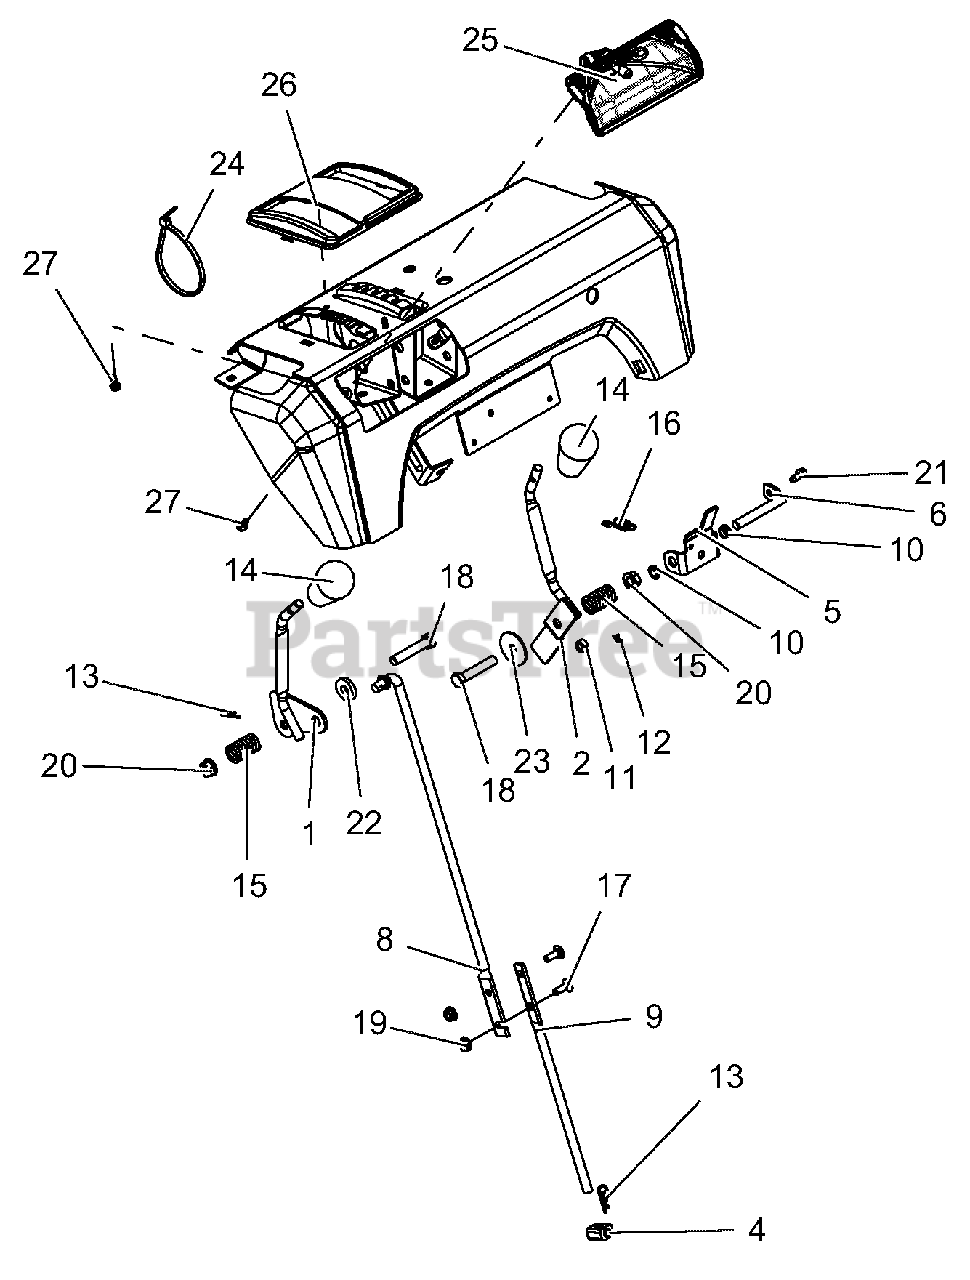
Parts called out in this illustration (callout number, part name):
1	WELDMENT, CONTROL LEVER(SHIFT)
2	WELDMENT, CONTROL LEVER (DEFL)
4	PIVOT,SHIFT ROD .375-16(TRUNN)
5	BRACKET, INTERLOCK ARM
6	ROD, PIVOT - INTERLOCK
8	ROD, SHIFT - UPPER
9	ROD, SHIFT - LOWER
10	BUSHING, POLYLINER-.38 SNAPIN
11	BSHG-SLV .265X.500X.219
12	PIN-HAIR INT .06X.18X.77
13	PIN-HAIR INT .08X.18X1.18 YWZC
14	KNOB,SOFT TEARDROP,PUSH-ON GRY
15	SG-COMP .125X.781X1.250
16	SPRING-EXT .047X.438X1.45
17	@BLT-RDHDSQNK .25-20X.75 G5YZ
18	@BLT-HEX .38-16X2.00 GR5 YWZC
19	@NUT-LK-CTR-FLG .25-20 YWZC
20	@NUT-LK-TOP-FLG .38-16 YWZC
21	SCR-TAP .25-20X.50 HWH TR YWZ
22	WSHR-FL-STL .406X1.00X.188 YWZ
23	WSHR-FL-STL .380X1.50X.062 YWZ
24	CABLE TIE LG 5-1/2
25	HEADLIGHT ASSY, HALOGEN 20W
26	BEZEL, SHIFT
27	SCR-TAP #10X.50 BOSS INDHXHD
